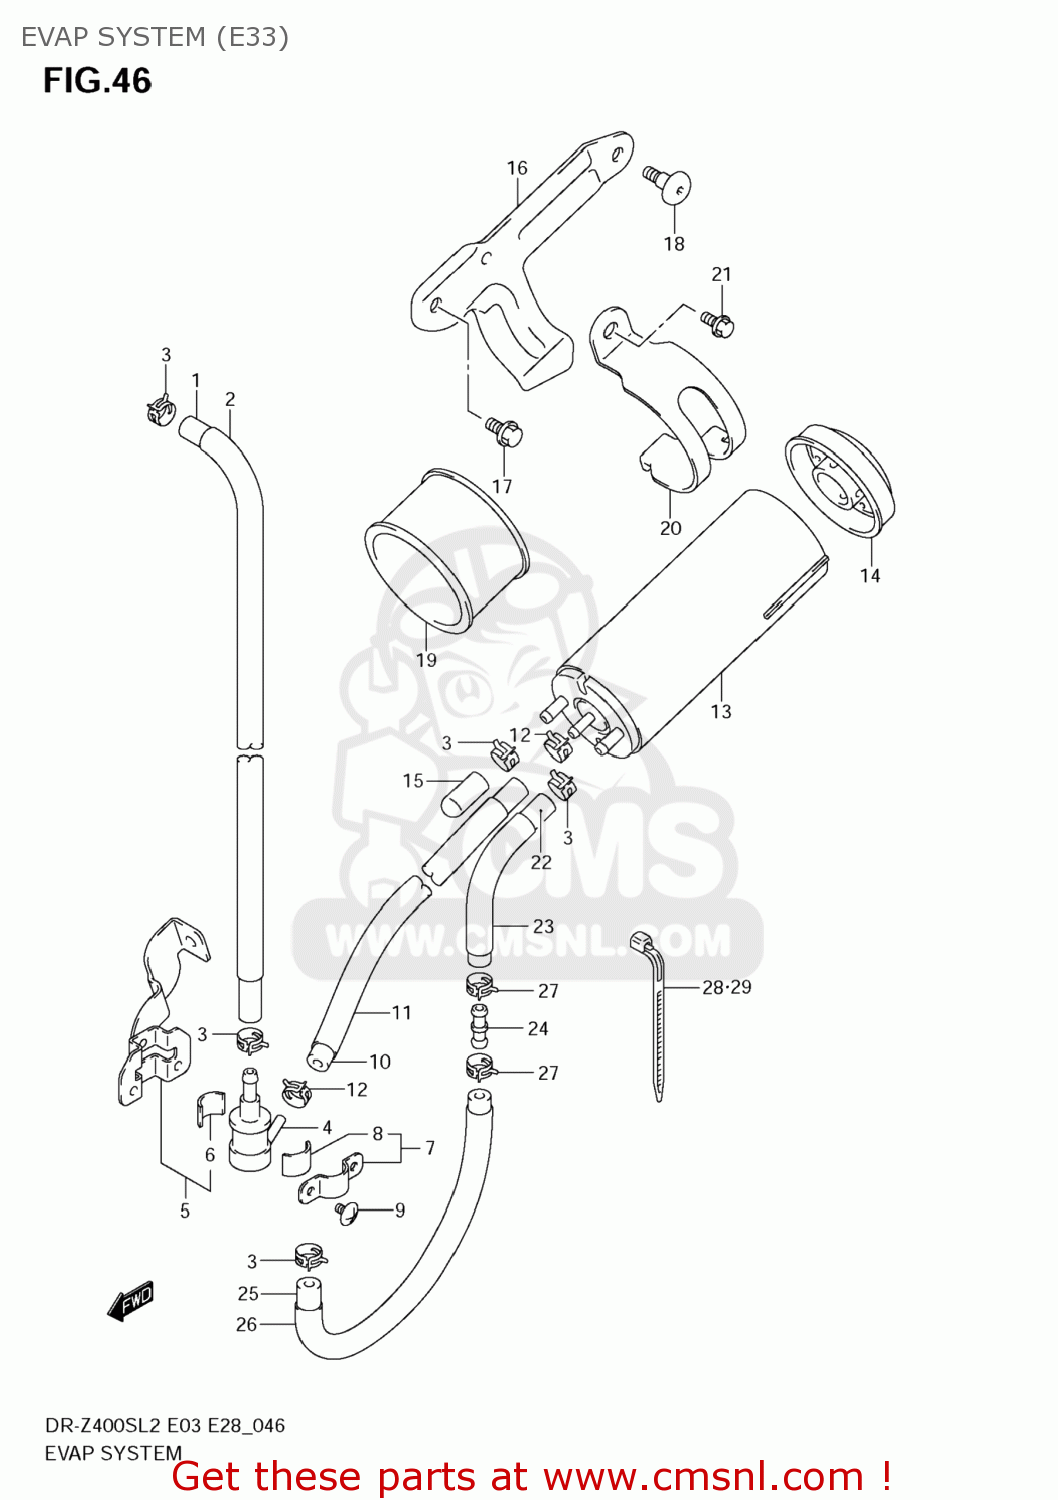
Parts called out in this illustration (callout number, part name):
1	HOSE,TANK & BREATHER VALVE
2	PROTECTOR(14.5X15.5X600)
3	CLIP
4	VALVE,FUEL TANK BREATHER
5	BRACKET,BREATHER VALVE
6	CUSHION
7	PLATE,FUEL TANK BREATHER NO.2
8	CUSHION
9	SCREW
10	HOSE,BREATHER VALVE & CANISTER
11	HOSE
12	CLIP
13	CANISTER ASSY,CHARCOAL
14	CAP,CANISTER
15	CAP,OD:11.5
16	BRACKET,CANISTER
17	BOLT
18	BOLT(6X16)
19	CUSHION,CANISTER
20	HOLDER,CANISTER
21	BOLT
22	HOSE,CSTR PURGE
23	PROTECTOR(14.5X15.5X600)
24	UNION
25	HOSE,CSTR & CARB PURGE NO.2
26	PROTECTOR(14.5X15.5X600)
27	CLIP
28	CLAMP(L:145)
29	CLAMP(L:125)
